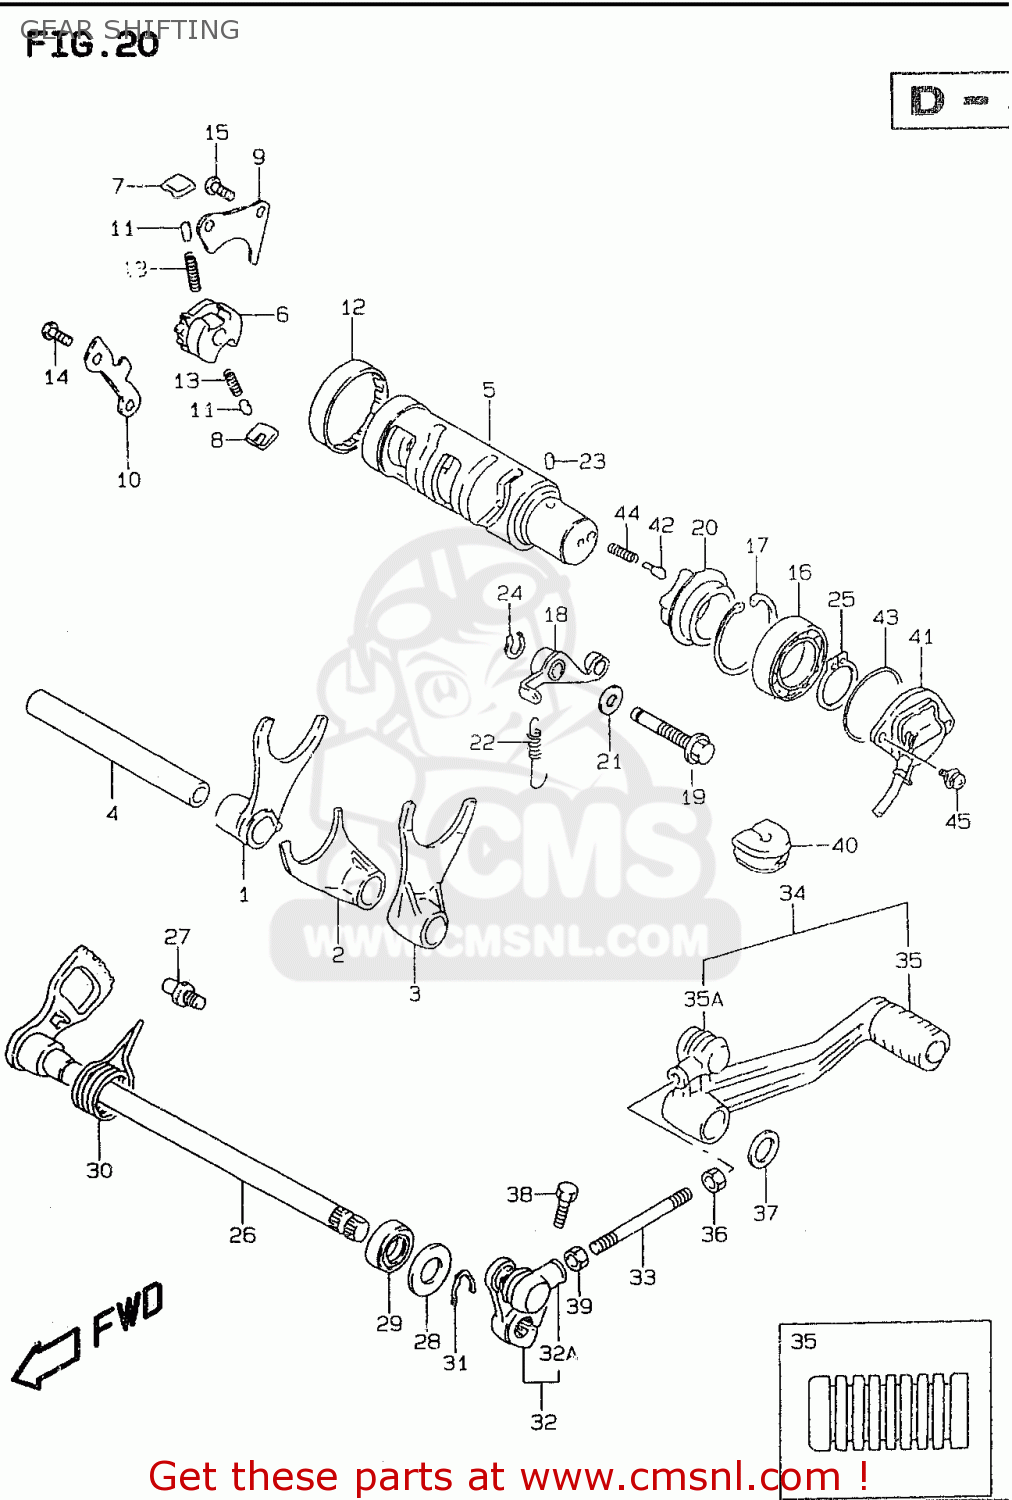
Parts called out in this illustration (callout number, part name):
1	FORK,GEAR SHIFT NO.1
2	FORK,GEAR SHIFT NO.2
3	FORK,GEAR SHIFT NO.3
4	SHAFT,GEAR SHIFT FORK(L:128)
5	CAM,GEAR SHIFT
6	GEAR,GEARSHIFT CAM DRIVE
7	PAWL,GEAR SHIFT NO.1
8	PAWL,GEAR SHIFT NO.2
9	LIFTER,GEAR SHIFT PAWL
10	GUIDE,GEAR SHIFT CAM
11	PIN(5X8)
12	BEARING(43X49X12)
13	SPRING
14	SCREW
15	SCREW
16	BEARING
17	CIRCLIP
18	STOPPER,GEAR SHIFT CAM
19	SHAFT,GEAR SHIFT CAM STOPPER
20	PLATE,STOPPER
21	GASKET(10X14X3.6) (NAS)
22	SPRING
23	PIN
24	CIRCLIP
25	CIRCLIP
26	SHAFT,GEAR SHIFT
27	STOPPER,GEAR SHIFT CAM
28	WASHER (12.5X27X1.6)
29	OIL SEAL
30	SPRING
31	CIRCLIP,12 MM
32	ARM,GEAR SHIFT LINK
32A	COVER,DUST
33	ROD,GEAR SHIFT LINK
34	LEVER ASSY,GEAR SHIFT
35	RUBBER,GEAR SHIFT PEDAL
35A	COVER,DUST
36	NUT
37	WASHER(18X24X1)
38	BOLT
39	NUT
40	GROMMET,LEADWIRE
41	TERMINAL BASE ASSY,NEUTRAL
42	PIN(5X15.5)
43	O RING(D:2.4,ID:35.5)
44	SPRING
45	SCREW
